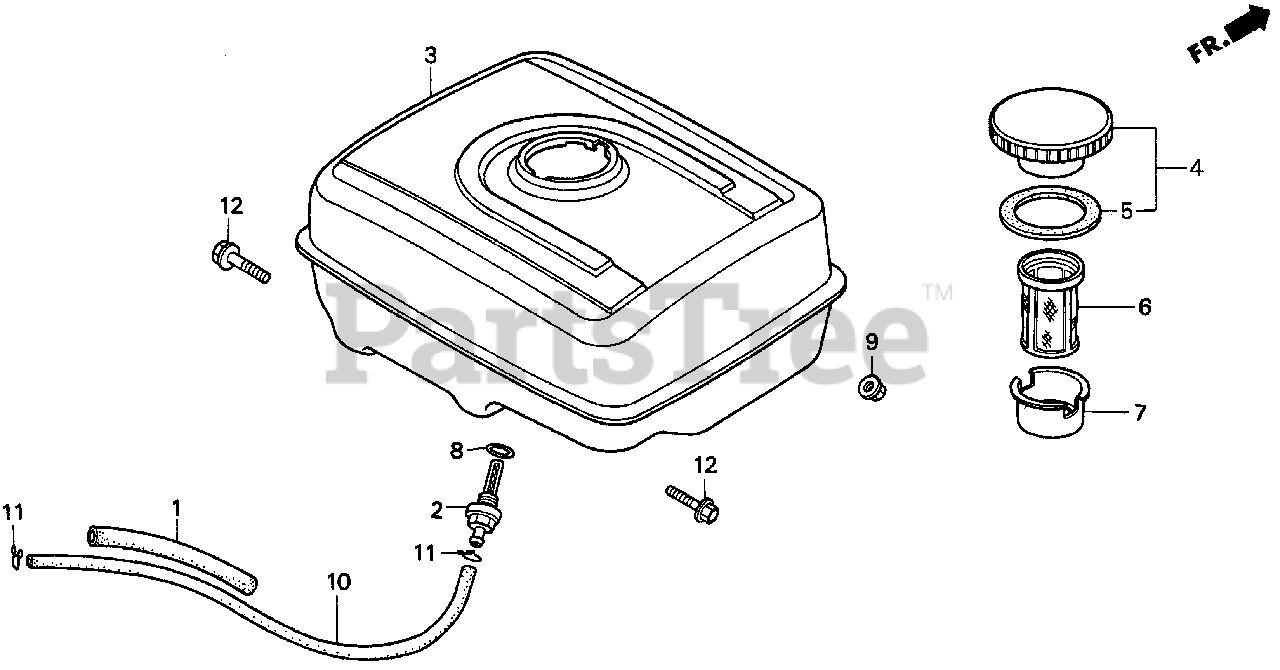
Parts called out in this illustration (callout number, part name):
1	RUBBER, SUPPORTER (107MM)
2	JOINT, FUEL TANK
3	TANK, FUEL *NH31* (MCKINLEY WHITE)
4	CAP, FUEL FILLER (BLACK) Use up to Engine SN 2115700.
5	GASKET, FUEL FILLER CAP Use from Engine SN 1543258.
6	FILTER, FUEL Use from Engine SN 1370795.
7	HOLDER, FUEL FILTER
8	O-RING (14MM) (ARAI) Use up to Engine SN 2949254.
8	O-RING (14MM) (NOK)
9	NUT, FLANGE (8MM)
10	BULK HOSE, FUEL (4.5X3000) (Honda Code 5137104). (4.5X140)
11	CLIP, TUBE (B8)
12	BOLT, FLANGE (8X25)
